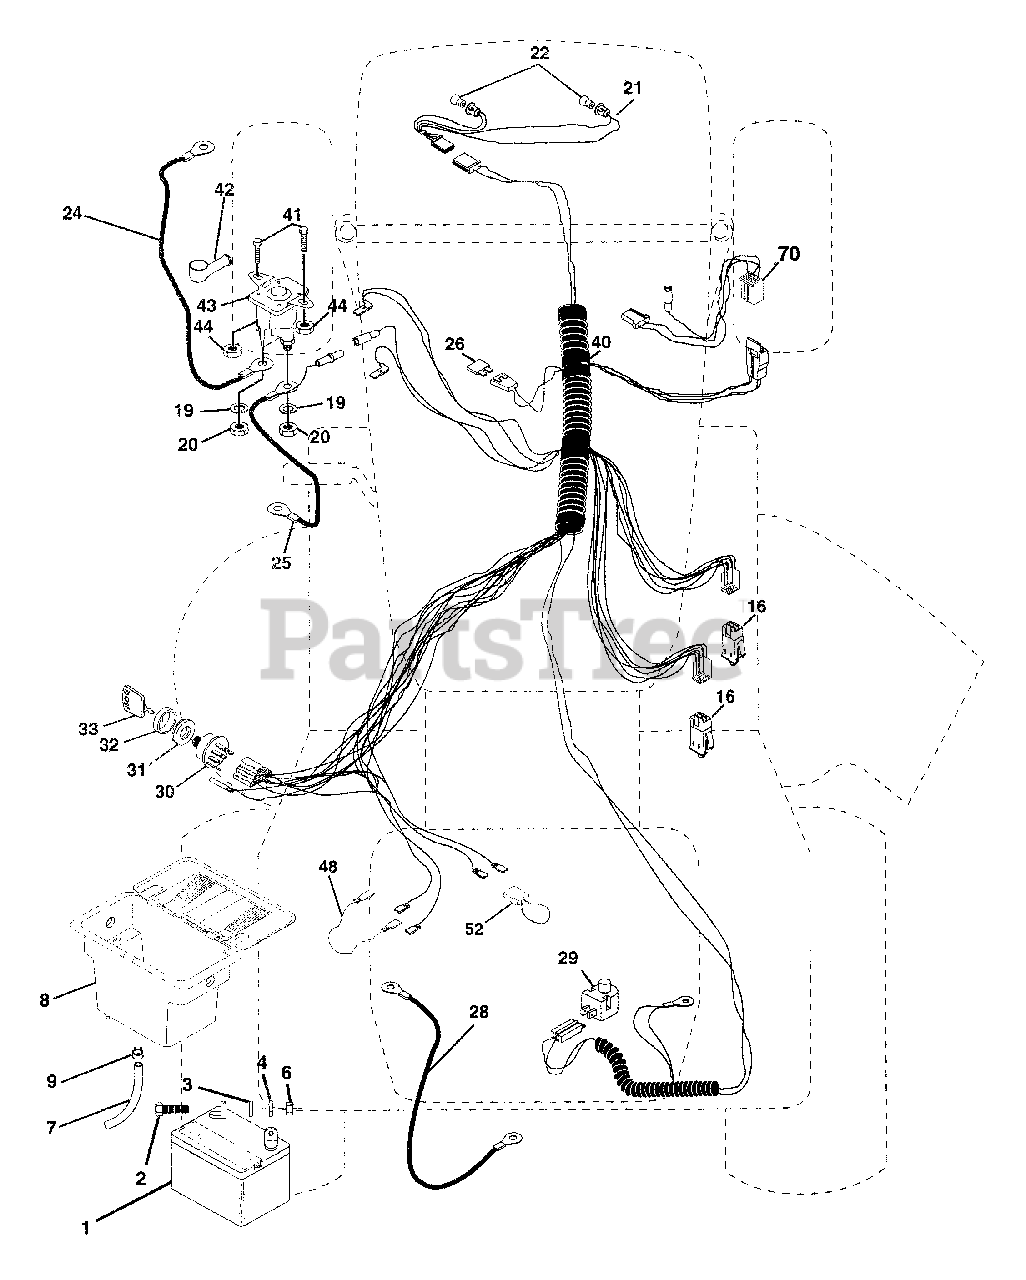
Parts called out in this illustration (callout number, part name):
1	Battery 12 Volt 25 AMP
2	Bolt Hex Hd 1/4-20unc X 3/4
3	Washer 9/32 X 5/8 X 16 Ga.
4	Washer Lock Hvy Helical 1/4
6	Nut Fin Hex 1/4-20 Unc
8	Case Battery Mech Hinge
16	Switch Interlock Push-In
19	Washer Lock 1/4
20	Nut Jam Hex 1/4-20 Unc
21	Harness Asm Light W/4152j
22	Bulb Light #1156
24	Cable Battery 6 Ga 11" red
25	Cable Battery 6 Ga 44" red w/16 wire
26	Fuse 30 AMP Auto Green
28	Cable Ground 6 Ga 12" black
29	Switch Plunger Nc Gray
30	Switch Ign 4 pos w/lights
31	Nut Ignition
32	Cover Sw Ignition
33	Key Ign Modelled Generic
40	Harness Ign.
41	Bolt Blk Fin Hex 1/4 - 20 x 1/2
42	Cover Terminal Red
43	Solenoid
44	Nut Keps Hex 1/4-20 Unc
48	Adapter Ammeter Rectangular
52	Protection Wire Loop
70	Harness, Eng. B&S/Tec Dual
